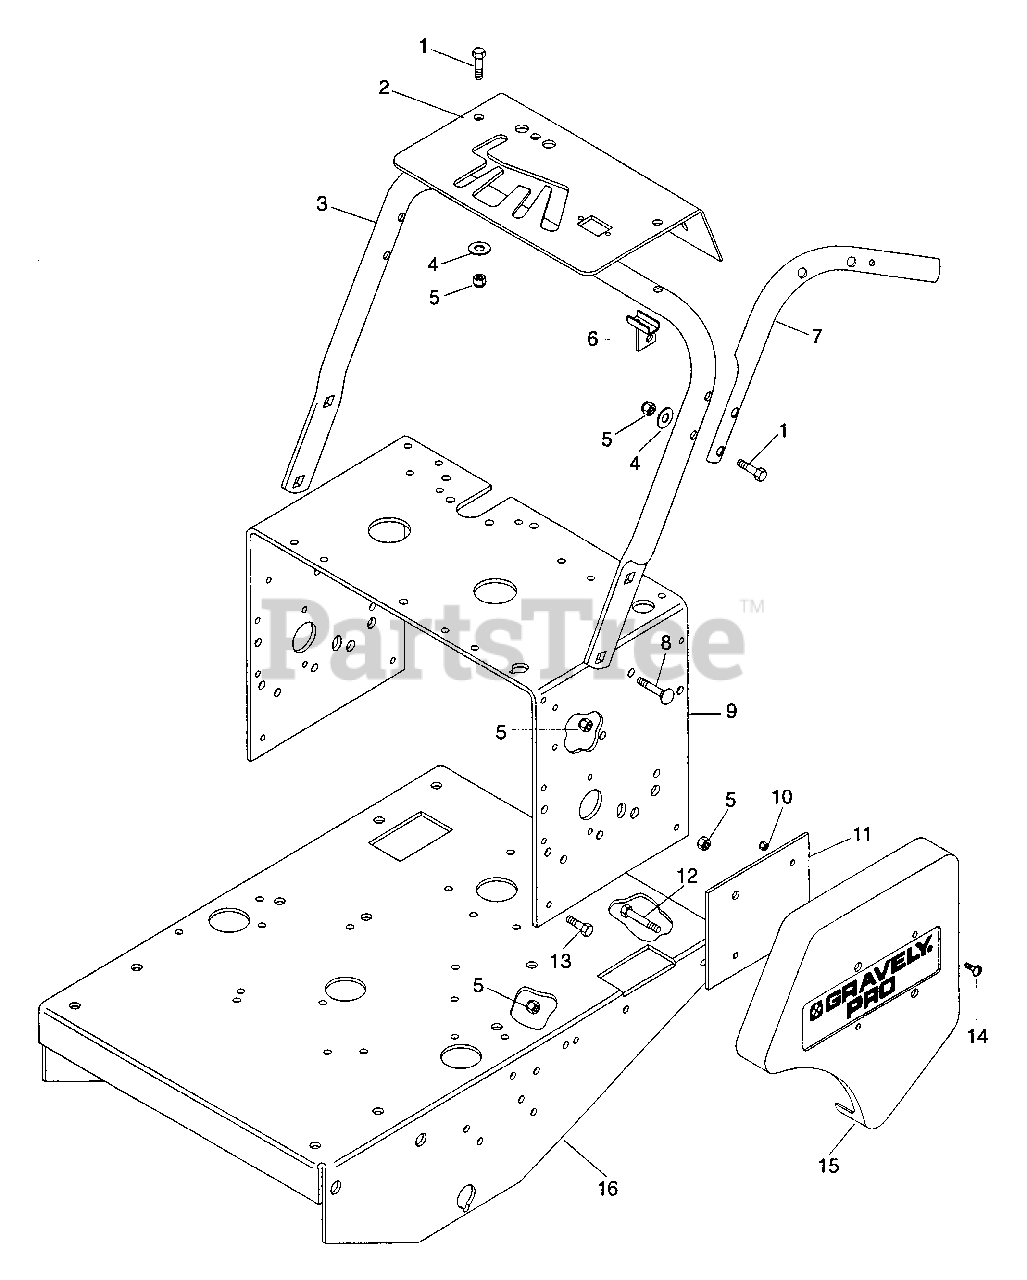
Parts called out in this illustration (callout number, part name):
1	Bolt-Hex .38-16 x 2.00 Grade 5
2	Panel, Silk Screened
3	Tube, Handlebar Mounting
4	Washer-Flat-Steel .406 x .812 x .065
5	Nut-Locking-Nylon .375-16 Grade 2
6	Weldment, PTO Lever Mounting
7	Handlebar Left Hand
7	Handlebar Right Hand
8	Bolt-Round Head Square Neck .38-16 x 1.0
9	Support, Handlebar
10	Nut-Locking-Nylon .250-20 Grade 2
11	Bracket, Belt Guard Left Hand
12	Bolt-Hex .38-16 x 1.38
13	Bolt-Hex .38-16 x 1.00 Grade 5
14	Screw-Machine .25-20
15	Guard, Belt Left Hand
15	Guard, Belt Right Hand
16	Weldment, Pro Frame
